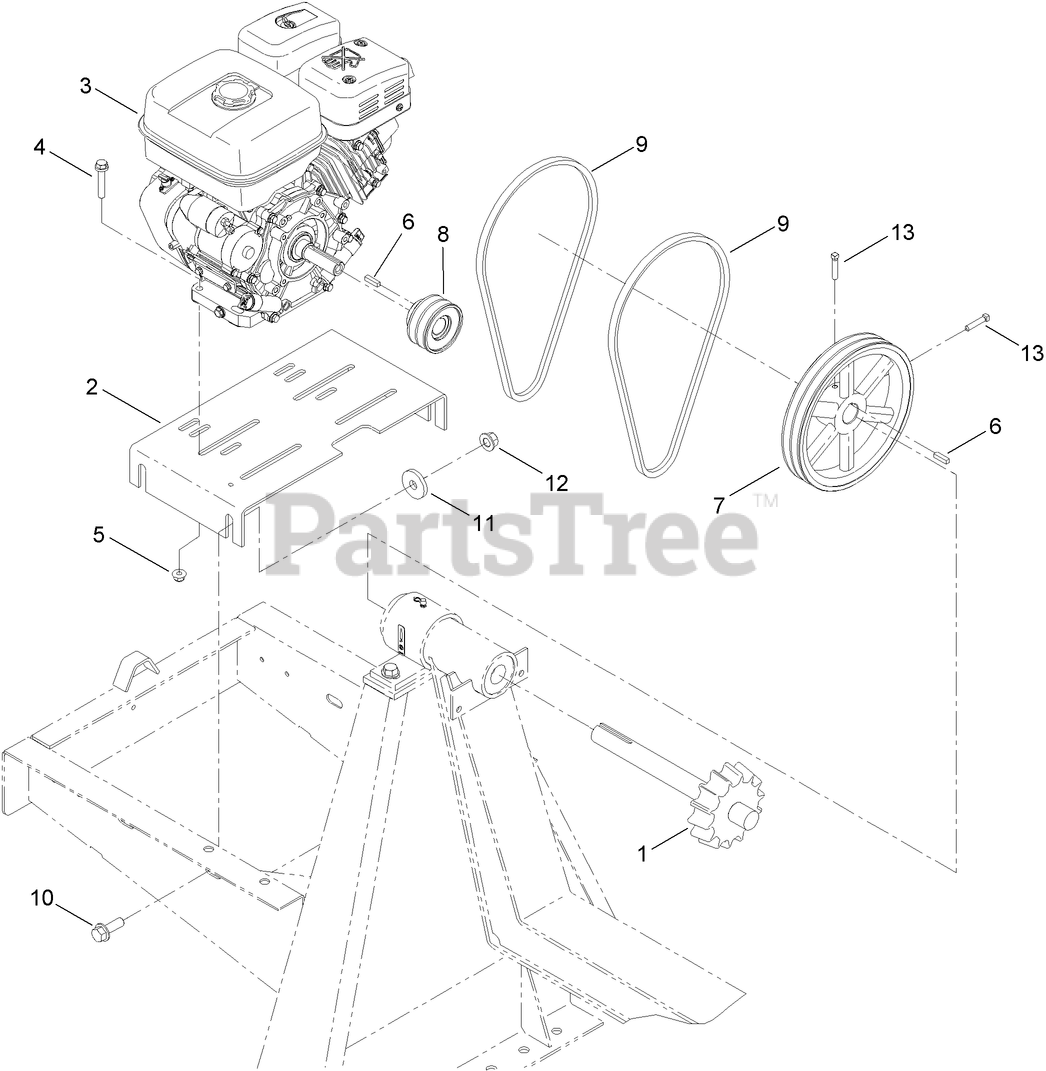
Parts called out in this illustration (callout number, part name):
1	SHAFT-DRIVE
2	BASE-MOTOR
3	ENGINE-HONDA, GX240
4	SCREW-HHF
5	NUT-HF, NI
8	SHEAVE
9	BELT-V
10	SCREW-HHF
11	WASHER-FLAT
12	NUT-LOCK
13	SCREW-SET
